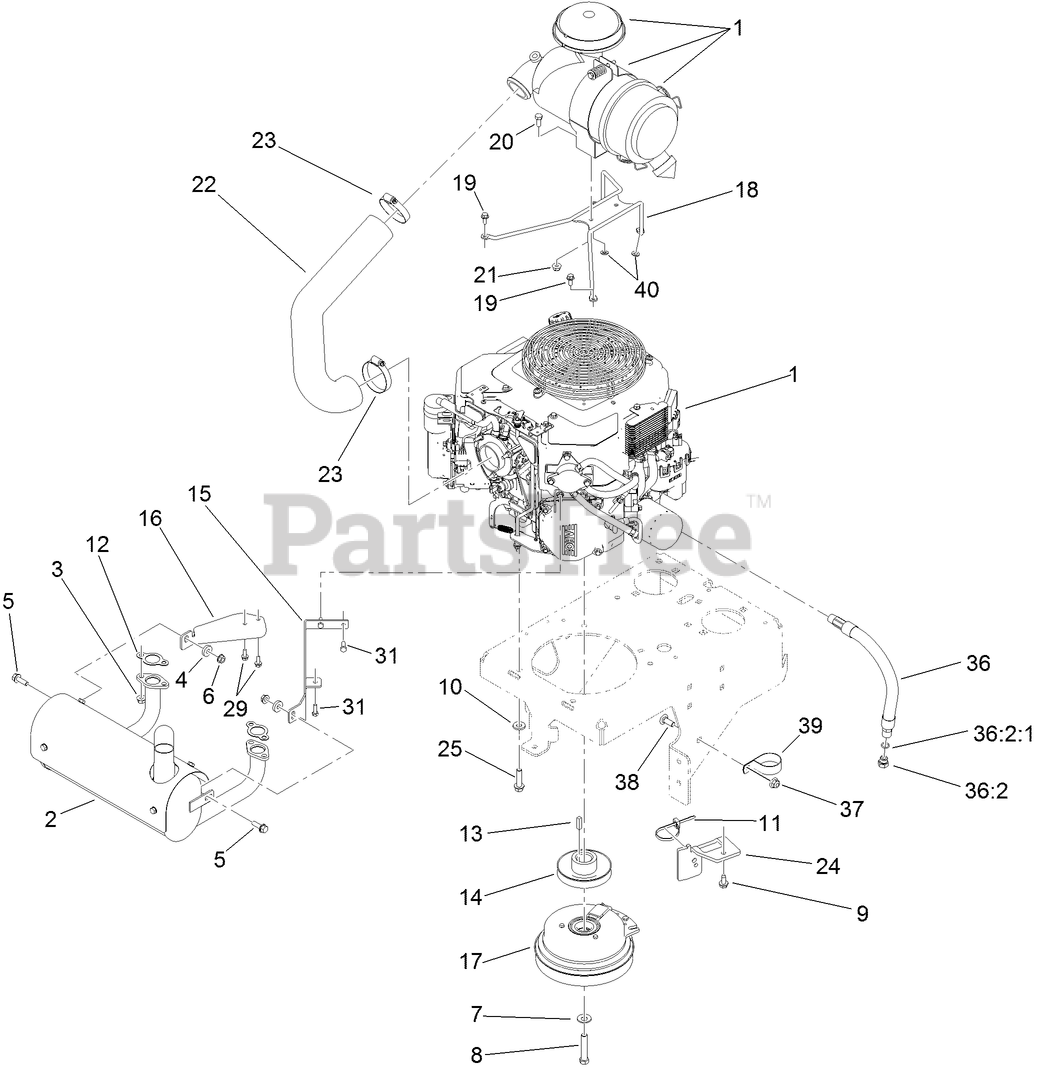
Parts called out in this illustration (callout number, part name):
2	MUFFLER
3	NUT-FLANGE
4	SPACER
5	SCREW-HHF
6	NUT-HF
7	WASHER-SPRING
8	SCREW-HH
9	SCREW-HWHTF
10	WASHER-BELLEVILLE
11	TIE-CABLE
12	GASKET-EXHAUST
14	PULLEY
15	BRACKET-MUFFLER, LH
16	BRACKET-MUFFLER, RH
17	CLUTCH
18	MOUNT-CLEANER, AIR
19	SCREW-HHF
20	SCREW-HH
21	NUT-HF, NI
22	HOSE-INTAKE, AIR
23	CLAMP-HOSE
24	BRACKET-ANCHOR, CLUTCH
25	SCREW-HWH
29	SCREW-HWHTF
31	SCREW-HH
36	OIL DRAIN HOSE ASM
36:2	PLUG-HH
36:2:1	O-RING
37	NUT-HF, NI
38	SCREW-CARR
39	CLAMP-R
40	WASHER-PLAIN
